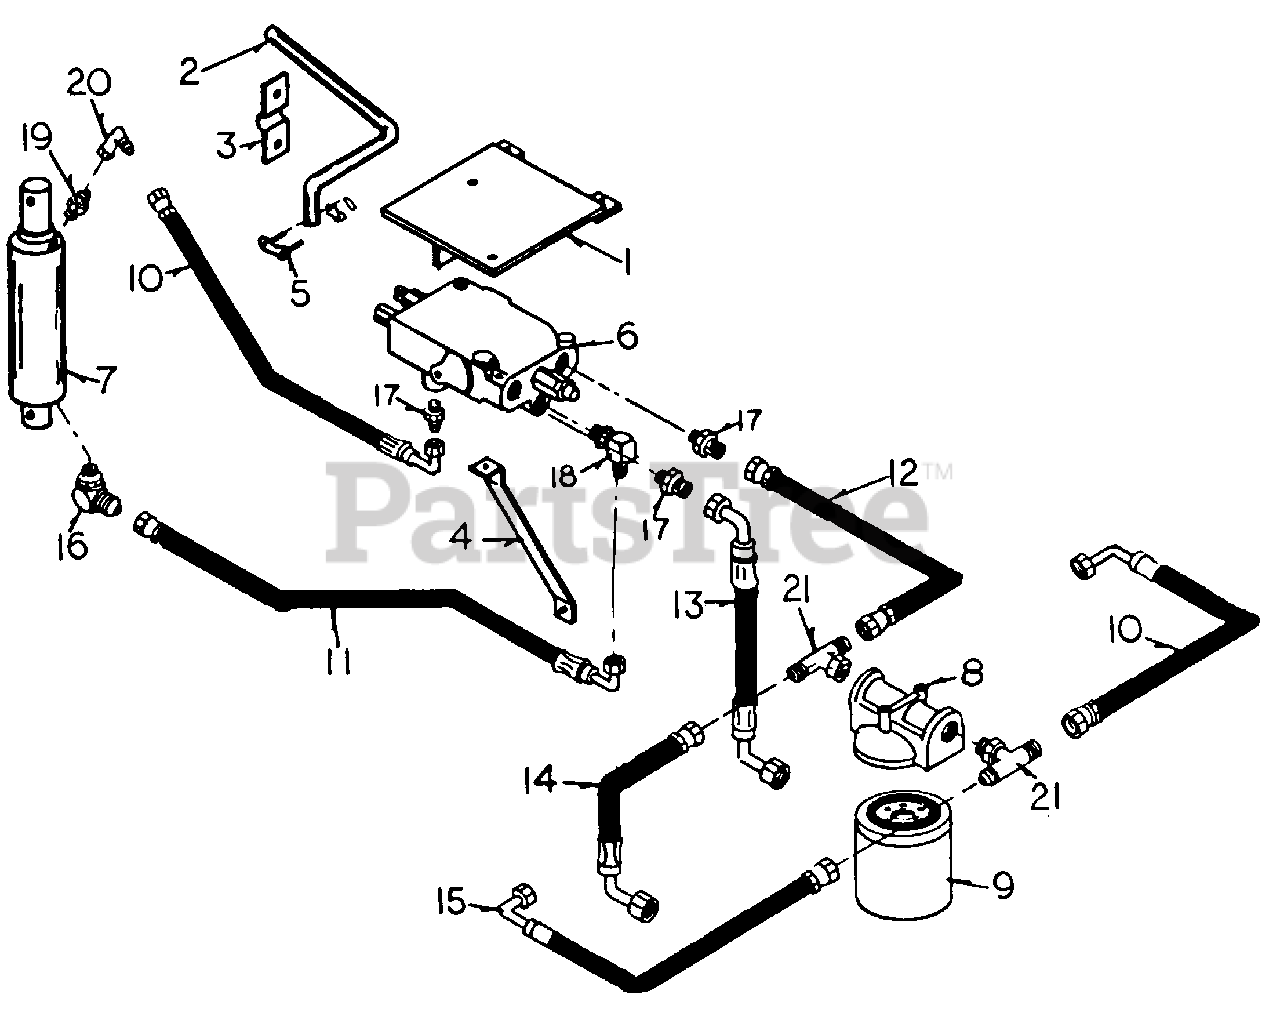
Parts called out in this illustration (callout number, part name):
1	Valve Mount
3	Bearing, Clutch Brake Cross Rod
4	Valve Support
5	Connecting Link, #50
8	Housing, Oil Filter 1
9	Element, Oil Filter
10	Hose, 3/8" ID x 26" Long
11	Hose, 3/8" ID x 31" Long
12	Hose, 3/8" ID x 20" Long
13	Hose, 3/8" ID x 13" Long
14	Hose, 3/8" ID x 11.5" Long
15	Hose, 3/8" ID x 21" Long
16	Male O-ring, 90ø Male 1 Tube Adp.
17	Male O-ring, Male 3 Tube Adp.
18	Male O-ring, 90ø Male 1 Tube Adp.
19	Male O-ring, Male 1 Tube Adp.
20	Male Tube, 90ø 37ø 1 Female Swivel Adp.
21	Male Tube, Male O-ring 2 Tee
